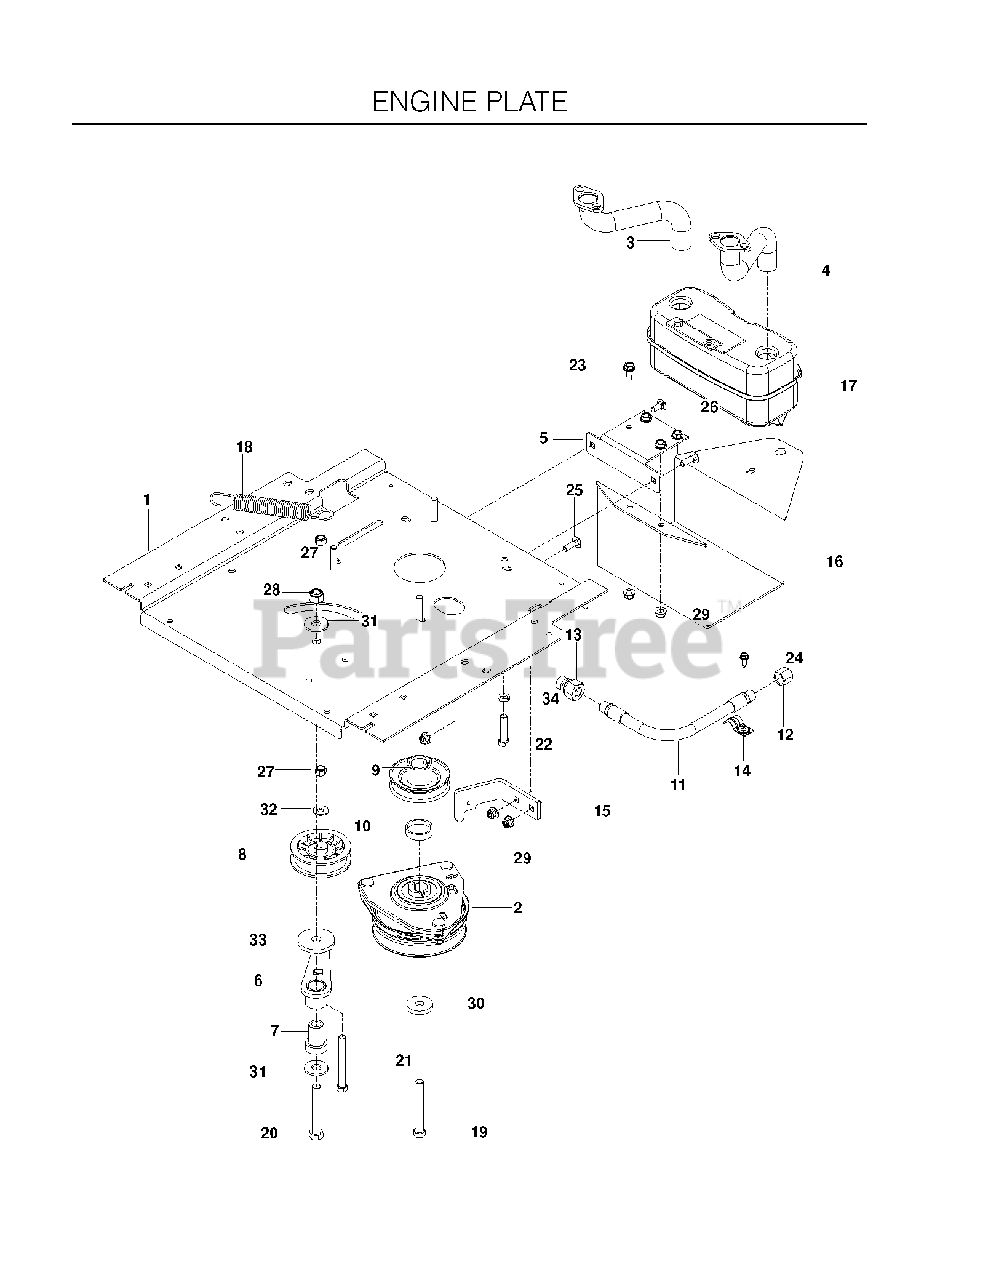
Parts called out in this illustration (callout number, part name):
1	PLATE, ENGINE BLK
3	TUBE.EXHAUST
4	TUBE.EXHAUST
5	BRACKET, MUFFLER, BLACK
6	IDLER ARM
7	IDLER SPINDLE
8	PULLEY, IDLER
9	PULLEY, ENGINE
11	OIL DRAIN HOSE
12	DRAIN CAP
13	ADAPTER, OIL DRAIN
15	CLUTCH STOP OGR BLK
16	GUARD, MUFFLER, BLACK
17	MUFFLER ASM TWIN
18	SPRING, DECK DRIVE
19	HCS 7/16-20 X 2.5 GR8
20	HCS 1/2C X 3 1/4
21	HCS 3/8-16X3 1/2 GR5
22	BOLT, HCS 3/8-16X1-3/4
23	BOLT 5/16-18 X 3/4
24	SCREW 1/4 X 5/8
25	RHSNB 5/16C X 1
26	BOLT 5/16C X 3/4" CARRIAGE
27	NUT 3/8-16 NYLOC
28	NUT 1/2-13 HEX NYLOC ZD
29	5/16-18 NYLOC FLANGE NUT
31	WASH USS FLAT 1/2
32	WASHER 5/16 FLAT
33	HEAVY WASHER
34	SLW 3/8 STD
